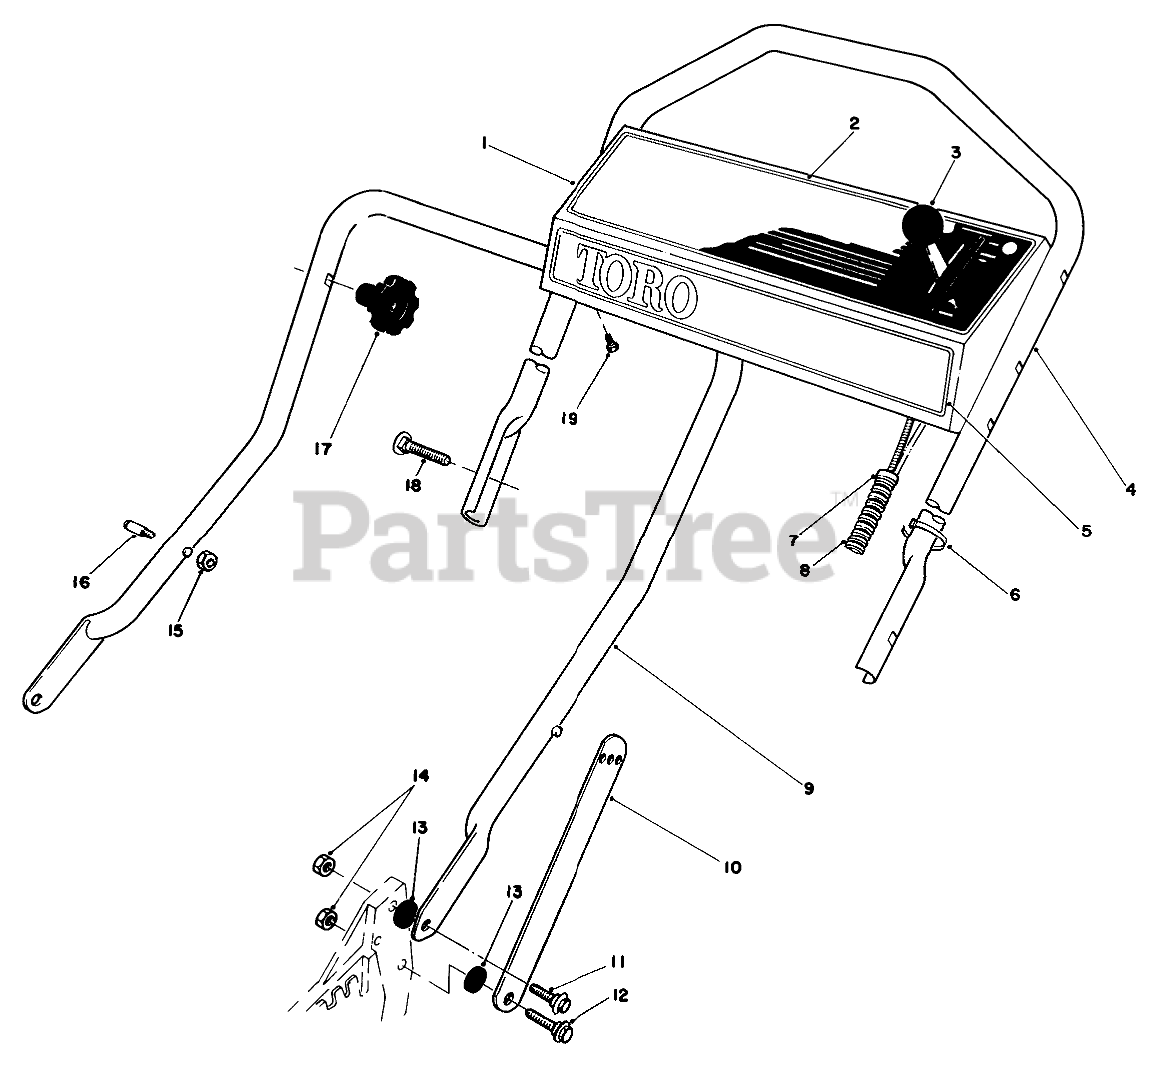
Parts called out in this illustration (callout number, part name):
1	Panel-Control (Incl. Ref. #2)
2	OBS INSTRUCTION DECAL
3	THROTTLE CONT-SERVICE
4	Handle-Upper
5	Decal-Toro
6	TIE-CABLE
7	FITTING-RING
8	CONTROL CABLE COVER
9	Handle-Lower
10	Handle Latch
11	SCREW-SHOULDER
12	SCREW-SHOULDER
13	SPACER
14	NUT-LOCK, NI
15	NUT-LOCK, NI
16	HANDLE PIN
18	5/16-18 X 2 HNDLE SCREW
19	SCREW-HWHTF
